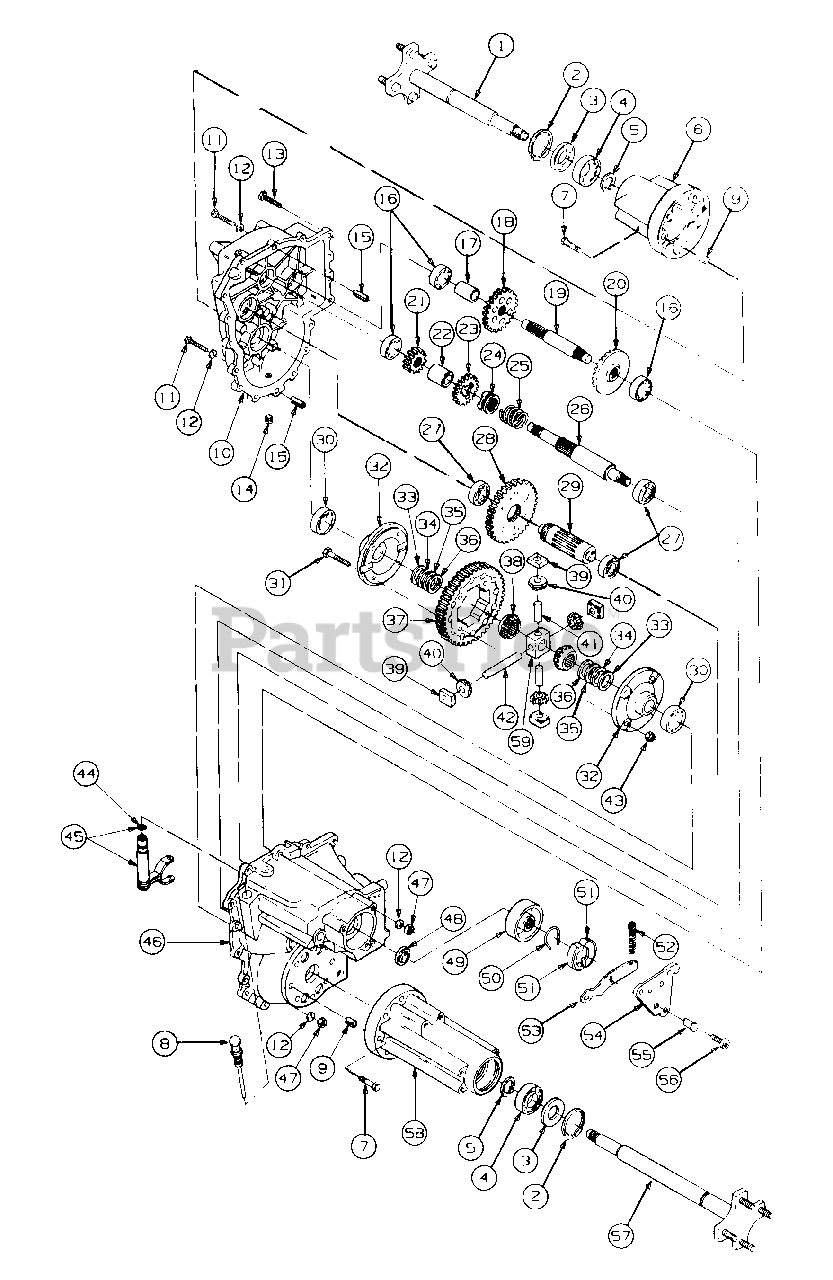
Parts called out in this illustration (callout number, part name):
1	Axle Assy, LH, 11.9" Lg
2	Ring, Inverted Retainer
3	Seal, Oil
4	Bearing
5	Ring, External Retaining
6	Housing, LH Axle
7	Screw, Hex L-Wash Tapp, 3/8-16 x 1.88
8	Dipstick, Oil
9	Bushing, Dowel
10	Housing, LH Differential
11	Screw, Hex Cap, 1/4-20 x 1.5
12	Washer, Flat, .25 x .62 x .052
13	Screw, Hex Wash Hd Tapp, 1/4-20 x 1.0
14	Plug, 1/2-14 NPTF
15	Pin, Slotted Spring, 7/16-1.0
16	Bearing, Ball
17	Spacer, .757 ID x 1.0 OD x 1.46
18	Gear, 27T Drive
19	Shaft, Drive
20	Gear, 36T Bevel
21	Gear, 16T Spur
22	Spacer, .885 ID x 1.125 OD x 1.4
23	Gear, 18T Shift
24	Collar, Drive
25	Spring, Compression, 1.015 ID x 1.6 Lg
26	Shaft, Shifter
27	Bearing, Ball, .787 x 1.85 x .551
28	Gear, 42T Spur
29	Shaft, 9T Output
30	Bearing, Ball
31	Screw, Hex Cap, 3/8-24 x 2.0
32	Cover,Differential
33	Washer, Flat, 1.0 x 1.56 x .010 Thk
34	Washer, Flat, 1.0 x 1.56 x .015 Thk
35	Washer, Flat, 1.0 x 1.56 x .020 Thk
36	Washer, Flat, 1.0 x 1.56 x .040 Thk
37	Gear, 60T Bull
38	Gear, 14T Differential Side
39	Block, Differential Thrust
40	Gear, 10T Differential Pinion
41	Shaft, Cross
42	Shaft, Cross, .50 OD x 3.485 Lg
43	Nut, Hex Lock, 3/8-24
44	O-Ring, 3/8 ID x 1/2 OD
45	Yoke Assy, Shift
46	Housing, RH Differential
47	Nut, Hex Center Lock, 1/4-20
48	Seal, Shift Shaft
49	Drum, Brake
50	Spring, Brake
51	Shoe, Brake
52	Spring, Compression
53	Arm, Brake
54	Plate, Brake
55	Actuator, Brake Shoe
56	Screw, Low Hd Cap, 3/8-16 x .75
57	Axle Assy, RH, 15.6 Lg
58	Housing, Axle - RH
59	Block, Differential Pinion
